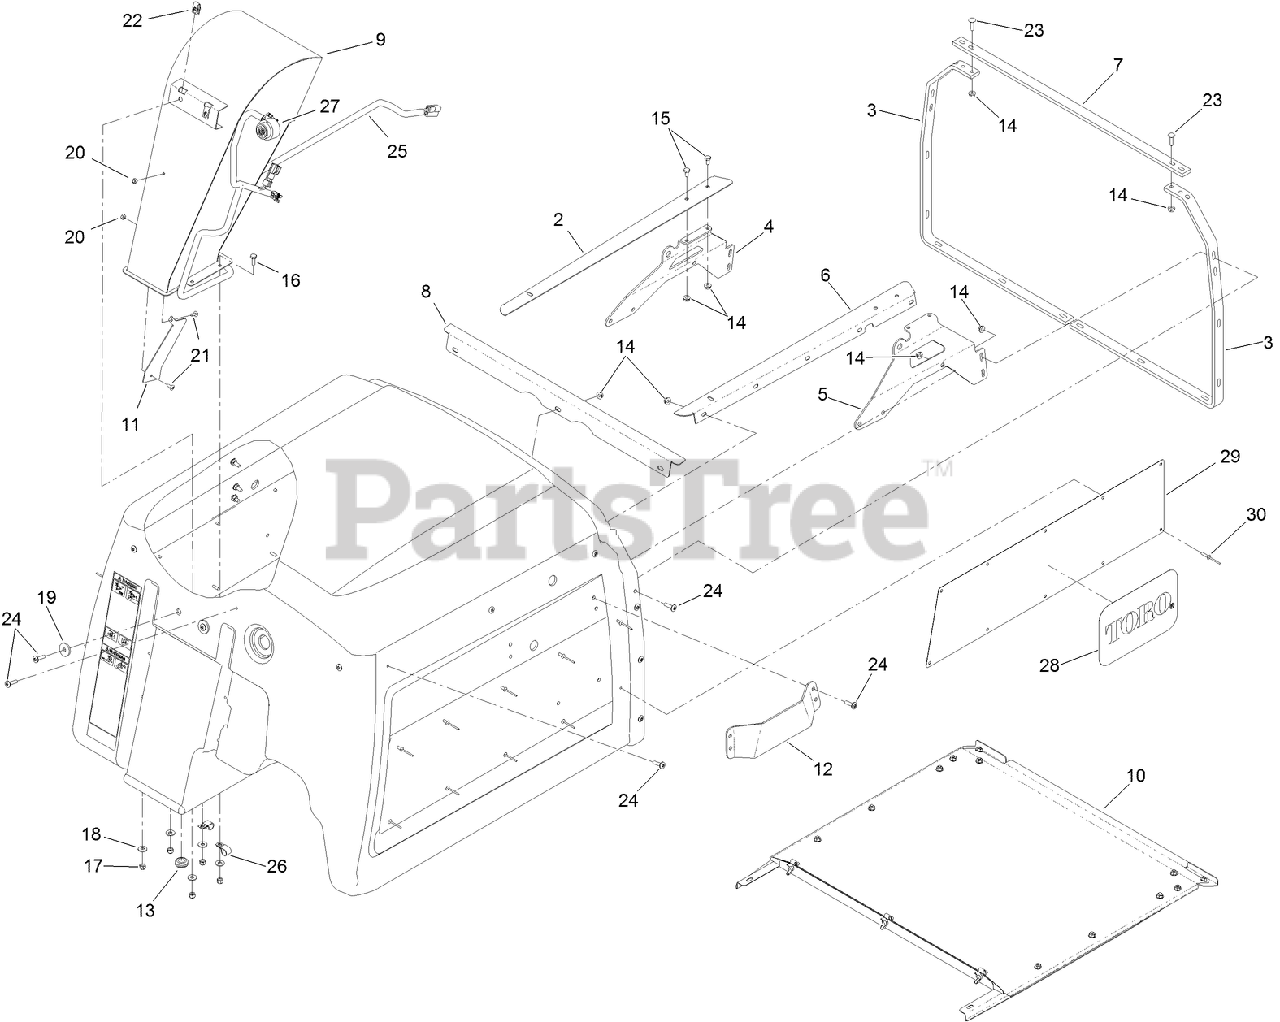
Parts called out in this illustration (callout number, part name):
2	ANGLE-SCREEN TRACK, RH
3	REINFORCEMENT-HOPPER
4	BRACE-DOOR PIVOT, RH
5	BRACE-DOOR PIVOT, LH
6	ANGLE-SCREEN TRACK, LH
7	BRACKET-FRAME CONNECT
8	CHANNEL-SCREEN, FRONT
9	DIFFUSER
10	HOPPER SCREEN ASM
11	DEFLECTOR-DISCHARGE CHUTE
12	PLATE-GUARD
13	GROMMET
14	NUT-HF
15	SCREW-HH
16	SCREW-HH
17	NUT-LOCK, NI
18	WASHER-FLAT
19	WASHER
20	NUT-LOCK, NI
21	SCREW-PTH
23	SCREW-CARR
24	SCREW-TTH
25	HARNESS-WIRE, HOPPER
26	CLIP-LOOM
27	ALARM-TONE, DUAL
29	PLATE-HOPPER, SIDE
30	RIVET-TRIFOLD
